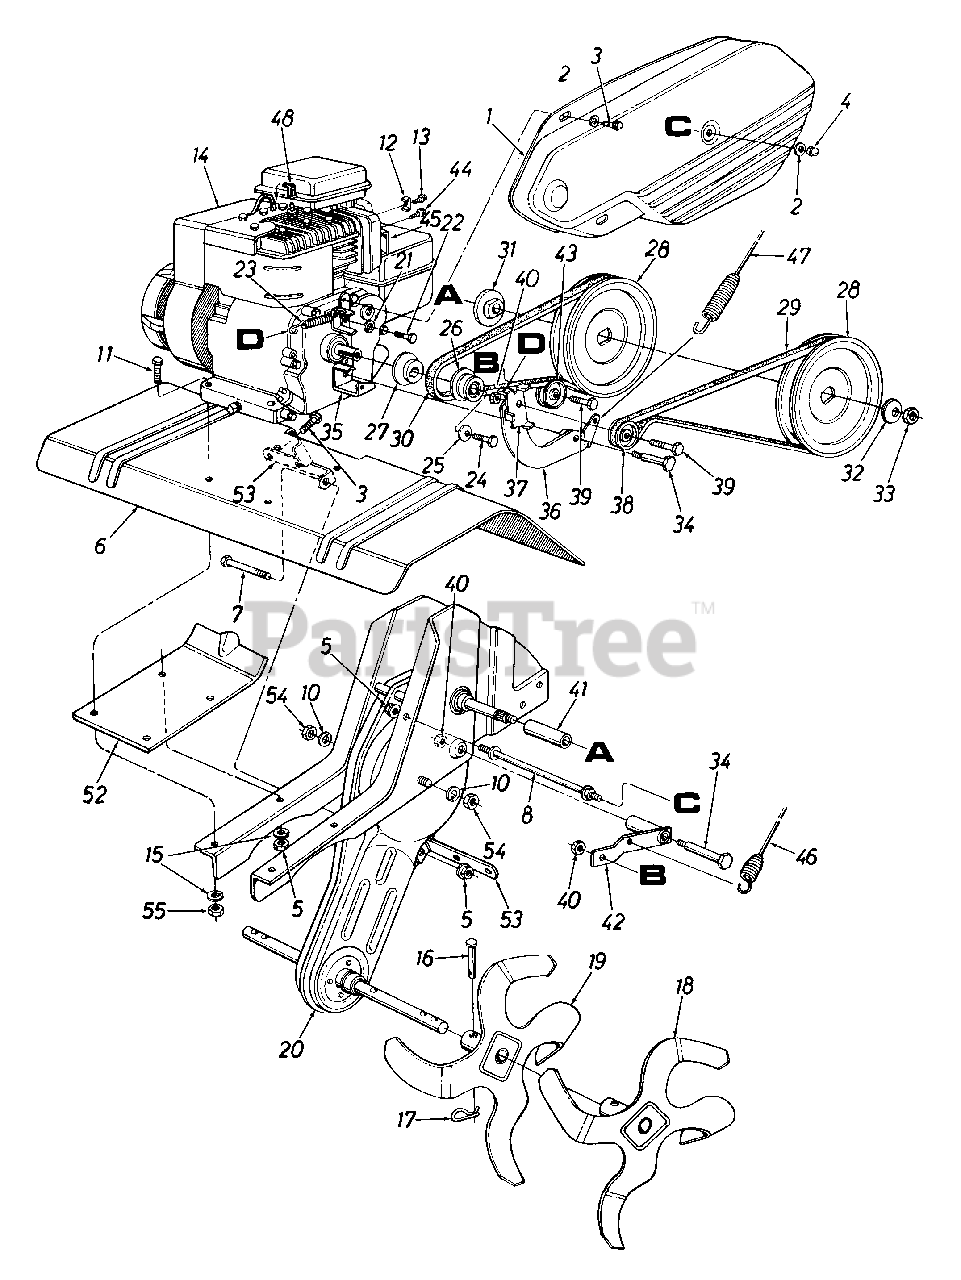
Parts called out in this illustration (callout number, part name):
2	Fl-Wash. .266" I.D. x .625" O.D.
3	Hex Wash. Hd. TT-Tap Scr. 1/4-20 x .5" Lg.
4	Hex L-Stop Nut 1/4-28 Thd.
5	Hex Flange Top L-Nut 5/16-18 Thd. (Gr. 5)
8	Belt Cover Bolt
10	L-Wash. 7/16" I.D.
11	Hex Bolt 5/16-18 x 1.75" Lg.
12	Casing Clamp
13	Hex Sems Scr. #10-32 x .62" Lg.
14	Engine
15	Spec. L-Nut 5/16" I.D.
16	Clevis Pin .375" Dia. x 1.75" Lg.
17	Internal Cotter Pin
20	Chain Case Ass'y. Comp.
21	L-Wash. 5/16" I.D.
22	Hex Bolt 5/16-24 x .5" Lg.
23	Return Spring 2.7" Lg.
24	Hex Bolt 3/8-24 x 1.25" Lg.
25	Bell-Wash. .396" I.D. x 1.14" O.D.
26	Outer Engine Pulley Half
27	Inner Engine Pulley Half
28	Fl-Pulley 6" Dia.
29	"V"-Belt (Reverse)
30	"V"-Belt (Forward)
31	Pulley Mounting Adapter
32	Bell-Wash. .535" I.D. x 1.5" O.D.
33	Hex Jam Nut 1/2-20 Thd. (Gr. 5)
34	Shld. Bolt .498" Dia. x 1.45" Lg.
35	Reverse Mounting Brkt.
36	Reverse Arm Ass'y.
38	Fl-Idler 2.12" O.D.
39	Hex Cap Bolt 3/8-16 x 1.25" Lg.
40	Hex Cent. Jam Nut 3/8-16 Thd.
41	Spacer .64" I.D. x 2.4" Lg.
42	Tine Idler Brkt. Ass'y.
43	Fl-Idler 2" O.D.
44	Hex Self-Tap Scr. #8-32 x .38" Lg.
45	Muffler Deflector
46	Clutch Control Cable - Forward
47	Clutch Control Cable - Reverse
48	Spark Plug Boot
54	Hex Nut 7/16-20 Thd.
55	Hex Nut 5/16-18 Thd. (Gr. 5)
